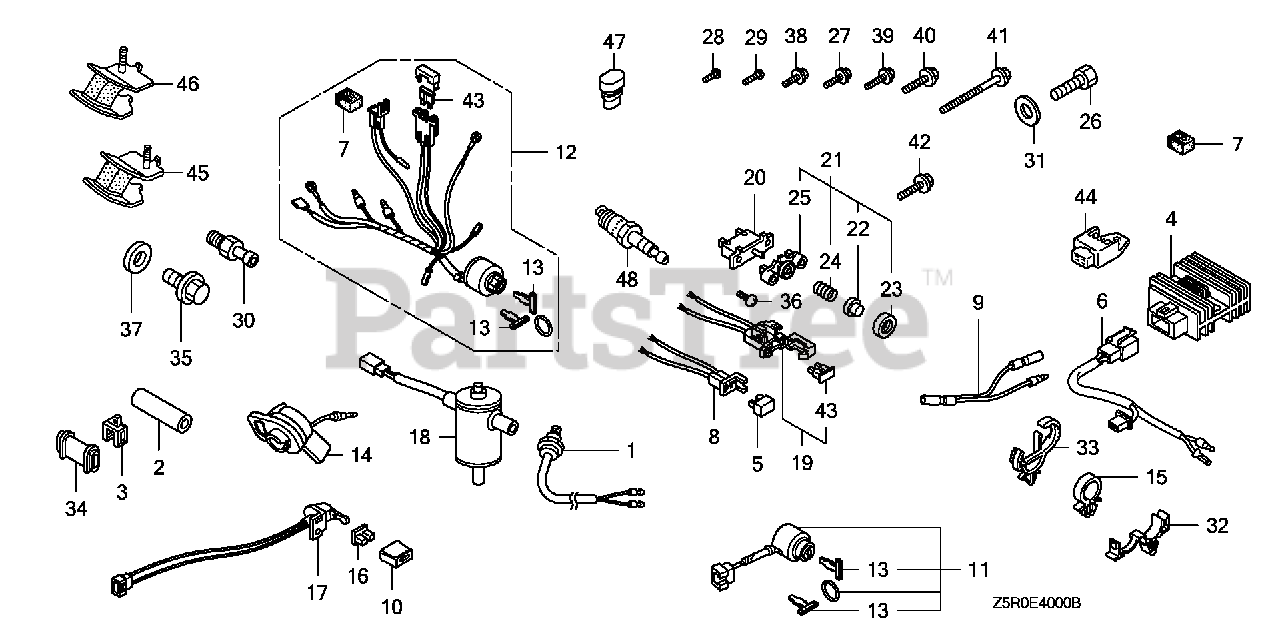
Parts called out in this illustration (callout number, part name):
3	CLIP, WIRE
5	RECTIFIER ASSY., SILICON (STANLEY)
5	RECTIFIER ASSY., SILICON (SHINDENGEN)
11	SWITCH ASSY., COMBINATION
13	KEY
19	CASE, FUSE
20	PROTECTOR, CIRCUIT (1.0A)
21	LENS ASSY., PROTECTOR
24	SPRING, COIL
25	HOLDER, LENS
29	SCREW, GLOVE BOX
40	BOLT, FLANGE (8X20)
43	FUSE, BLADE (5A)
